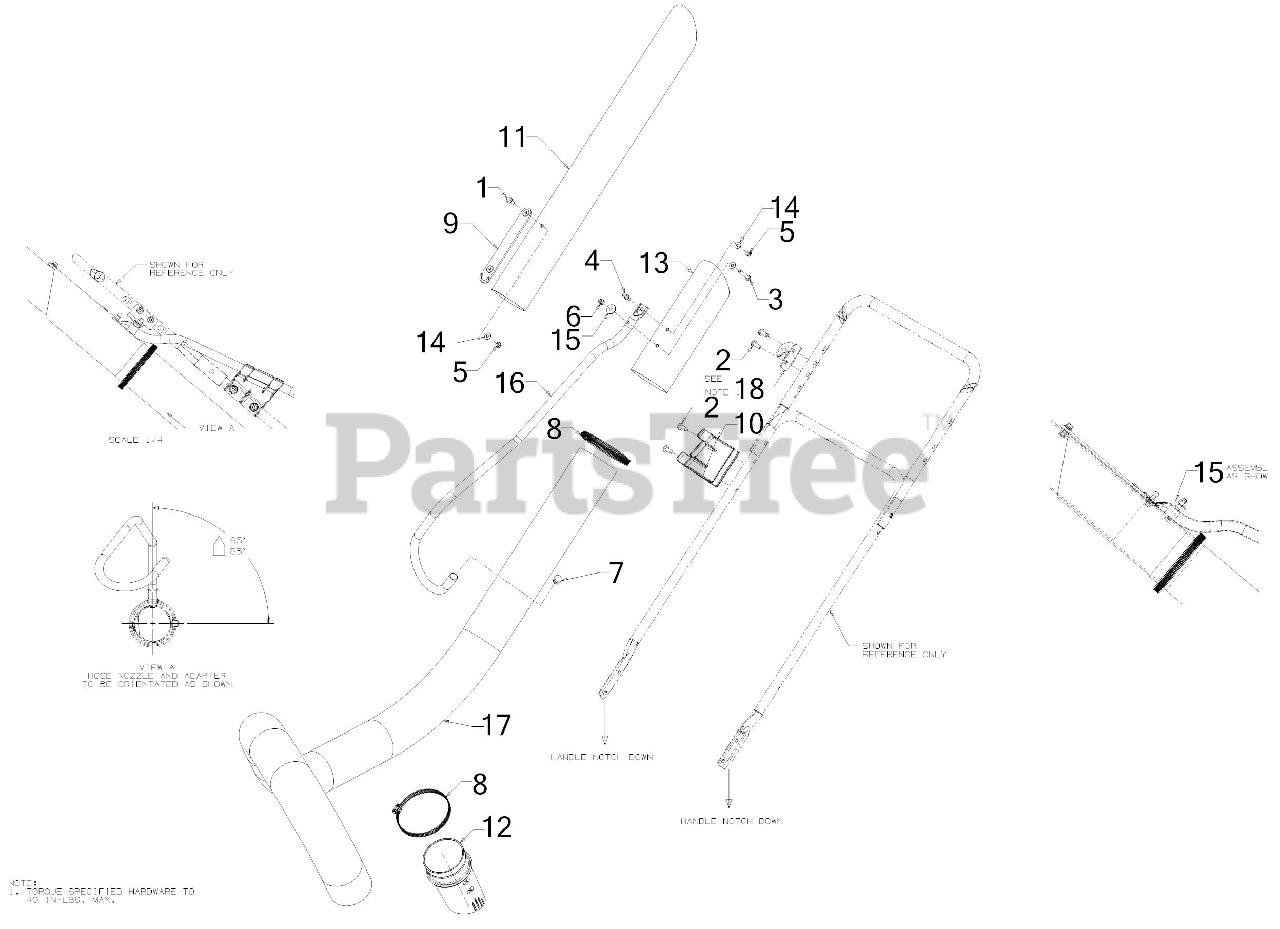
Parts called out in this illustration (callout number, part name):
1	SCREW 1/4-20 x .75 GR5
2	SCREW 5/16-18 x .750
3	BOLT 1/4-20X1.62 GR5
4	PIN 1/4-20
5	HEX NUT
6	HEX ACORN NUT
7	HANDLE PLUG
8	HOSE CLAMP
9	CHUTE STRAP
10	CLIP-HANDLE NOZZ
11	NOZZLE EXTENSION 3.625 x 31.00
12	HOSE ADAPTER
13	HOSE NOZZLE 3.875
14	FLAT WASHER .271:.630:.065
15	HOSE HANGER SPACER
16	NOZZLE HANDLE
17	VACUUM HOSE 4.0 x 75.0
18	UPPER HANDLE BRACKET
